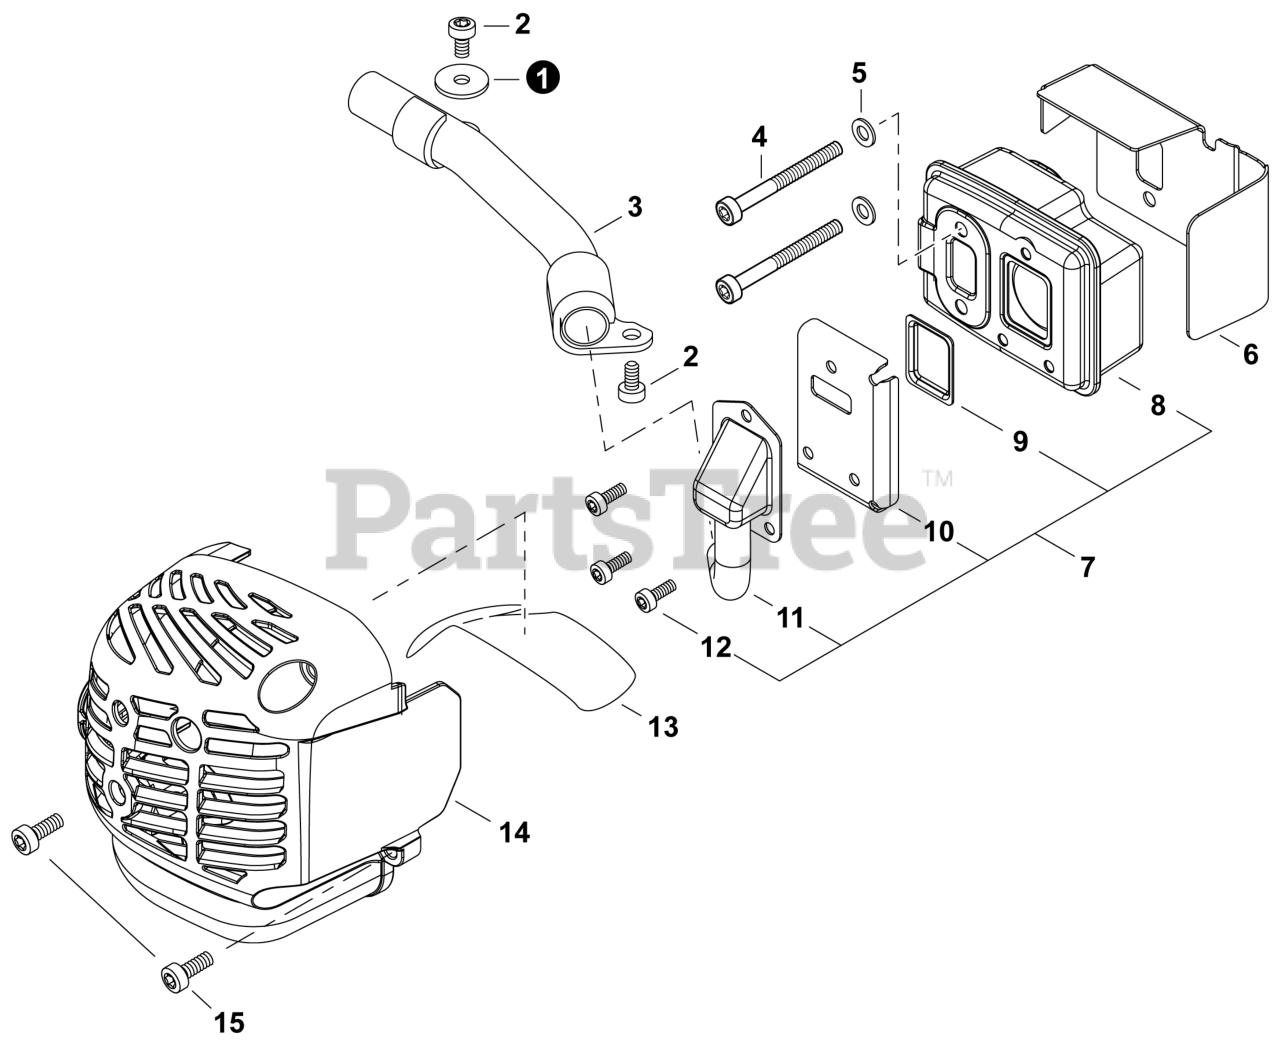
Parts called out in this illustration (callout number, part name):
1	WASHER 5
2	BOLT, TORX 5×10
3	GUIDE, EXHAUST
4	BOLT, TORX 5×55
5	WASHER 5.5×12×0.8
6	HEAT SHIELD, EXHAUST
7	MUFFLER ASSY
8	MUFFLER
9	SCREEN, SPARK ARRESTER
10	GASKET, EXHAUST
11	GUIDE, EXHAUST
12	BOLT, TORX 4×8
13	PLATE, INSULATOR
14	COVER, MUFFLER
15	BOLT, TORX 5×16
